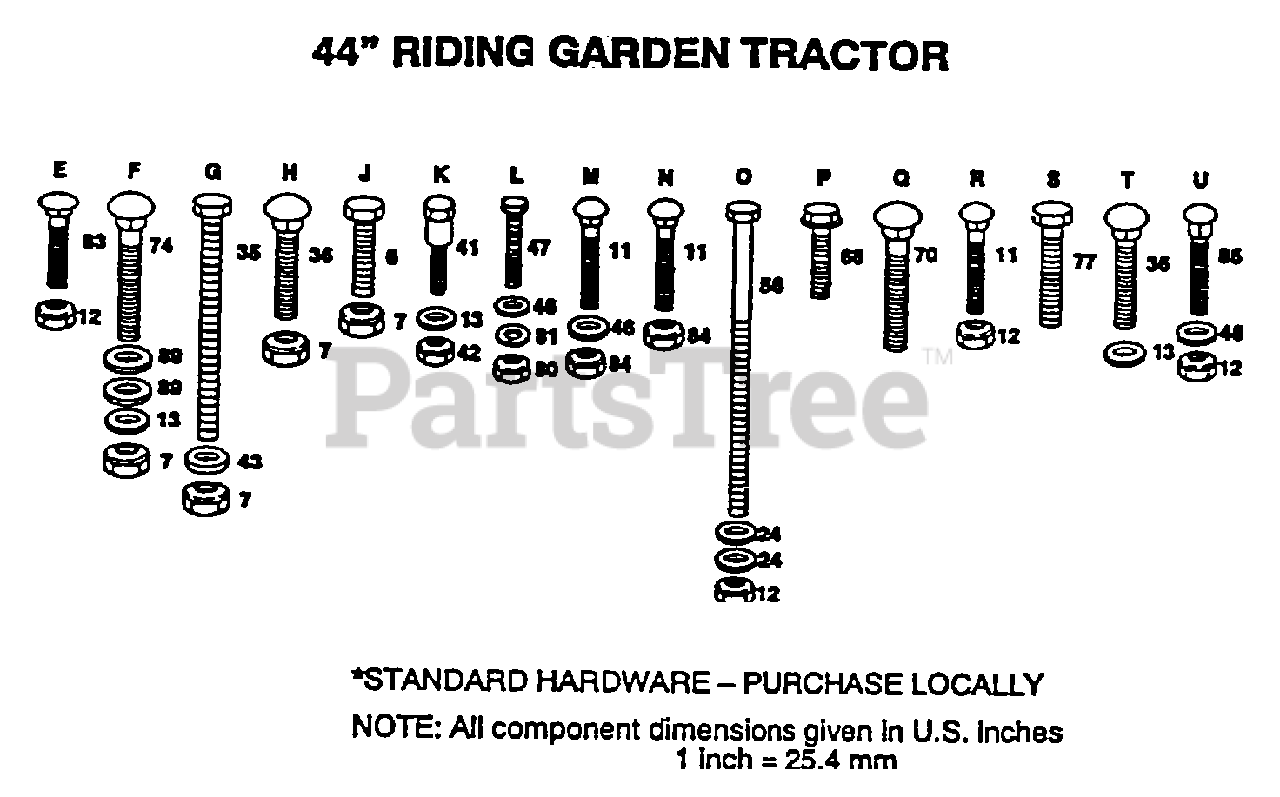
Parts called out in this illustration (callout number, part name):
11	BOLT
13	WASHER
24	WASHER M
35	BOLT - HEX 3/8 - 16 X 3
41	BOLT SHOULDER
42	LOCKNUT
43	WASHER
46	WASHER
48	ROD BRAKE YT
56	BOLT
68	SCREW
70	BOLT
74	BOLT
77	BOLT
80	NUT.HEX.5/16-18
81	LOCKWASHER
83	BOLT
86	LOCKWASHER
89	WASHER
